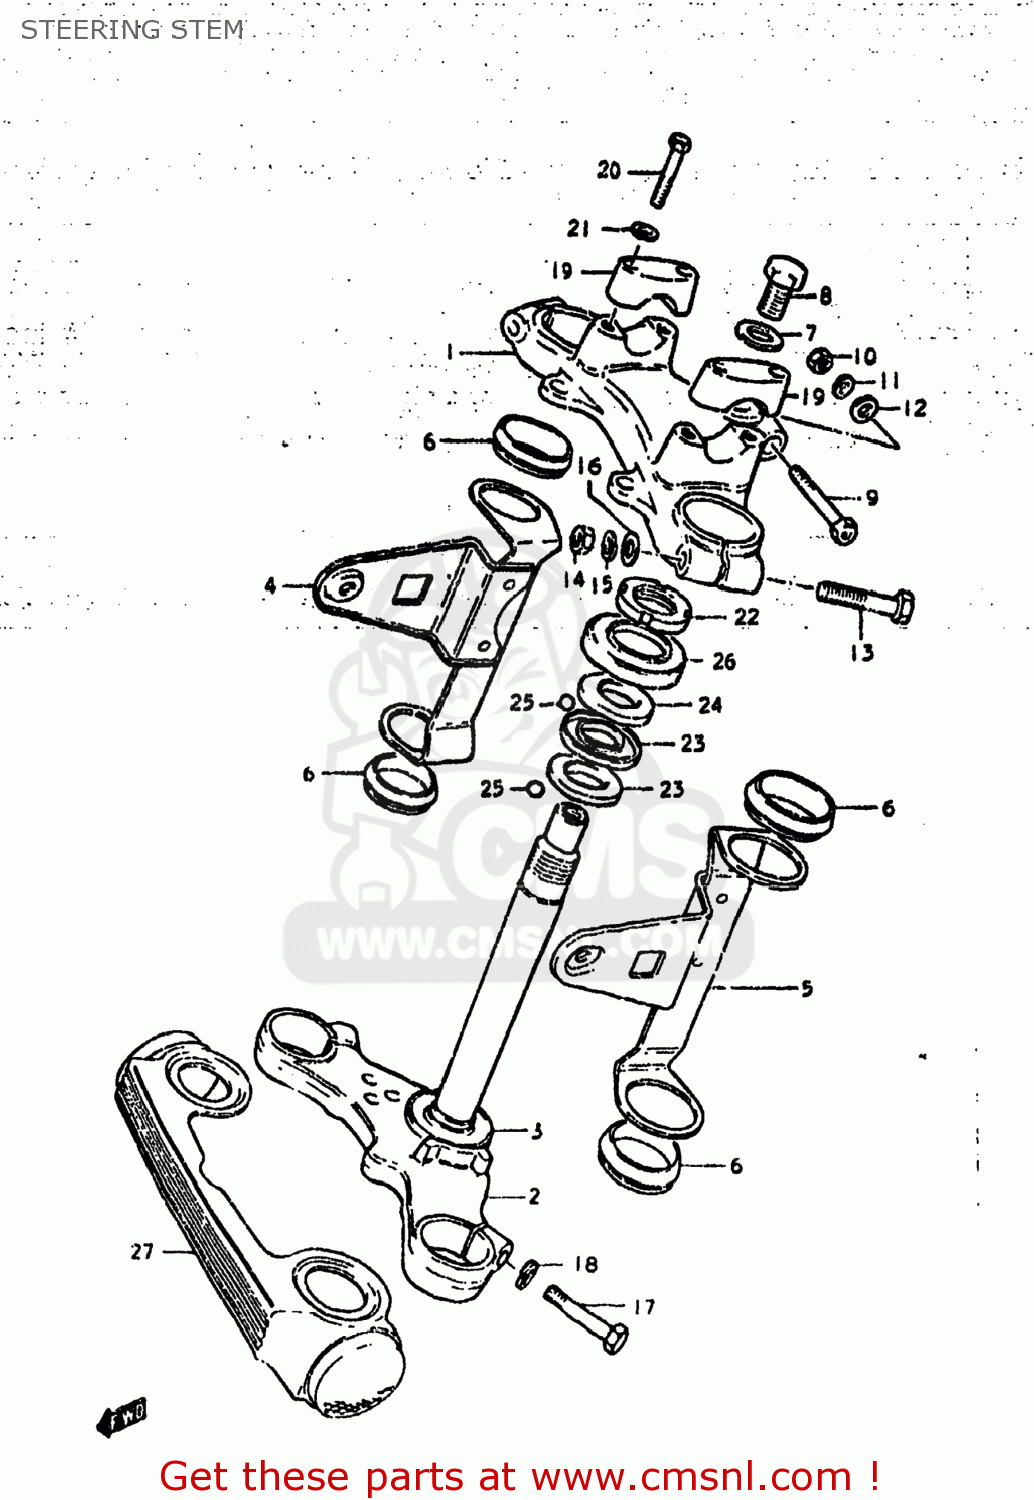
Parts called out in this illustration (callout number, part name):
1	HEAD,STEERING STEM
2	STEM,STEERING
3	RACE,STEERING OUTER LWR
4	BRACKET,HEADLAMP,RIGHT
5	BRACKET,HEADLAMP,LEFT
6	CUSHION,HEADLAMP BRACKET
7	WASHER
8	BOLT(12X20)
9	BOLT
10	NUT
11	LOCK WASHER
12	WASHER
13	BOLT
14	NUT, LOWER LH
15	LOCK WASHER
16	WASHER
17	BOLT 10X40
18	LOCK WASHER
19	HOLDER,HANDLE UPR
20	BOLT
21	LOCK WASHER
22	NUT,STEERING STEM(25X44X10)
23	LACE,STEERING INNER LWR
24	LACE,STEERING OUTER UPR
25	BALL
26	DUST SEAL,STEERING UPR
27	COVER,FR FORK
